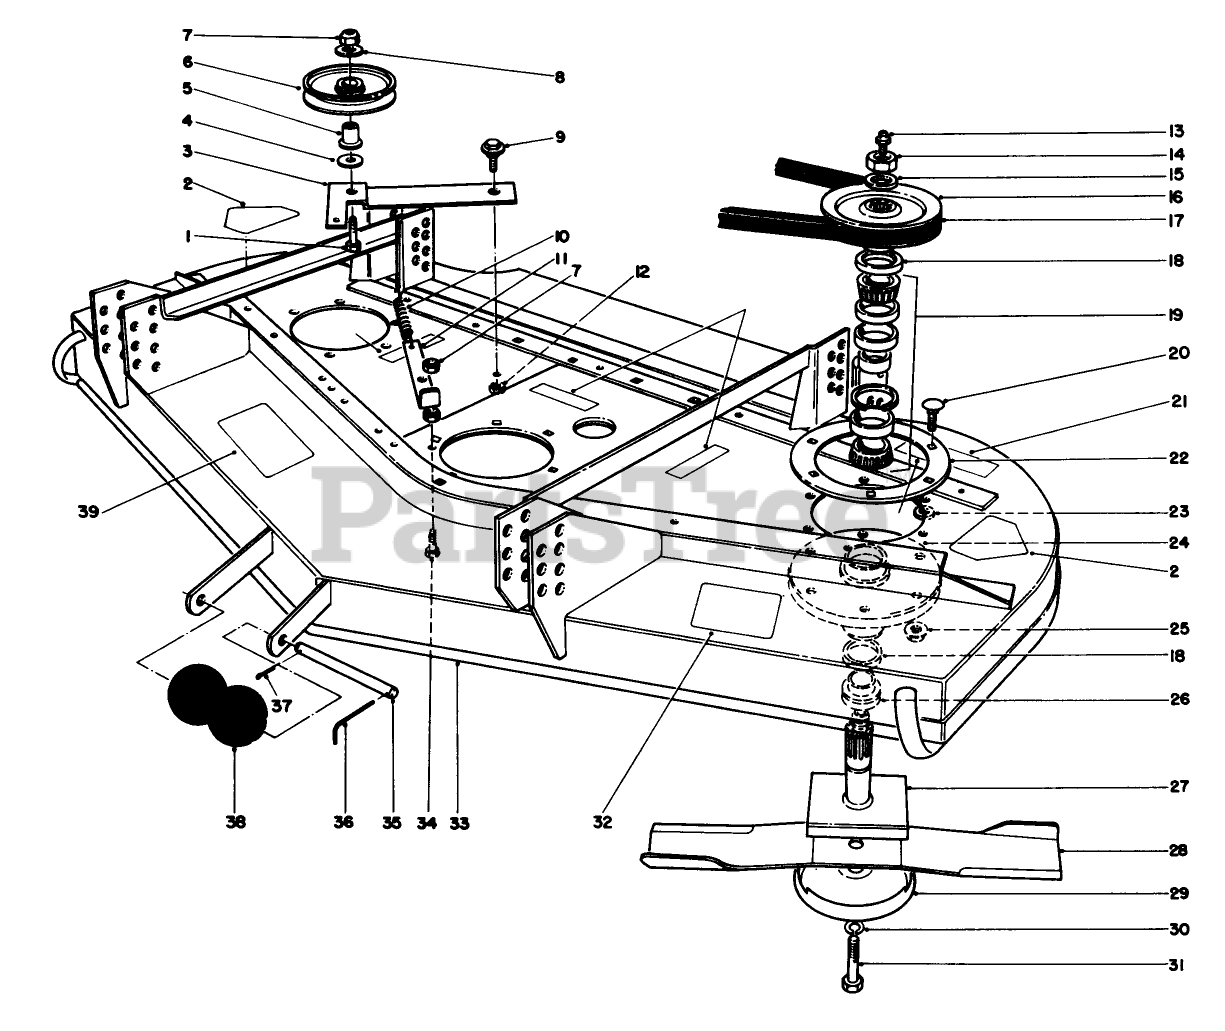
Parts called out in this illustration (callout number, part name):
1	SCREW-HH
2	DECAL-DANGER
3	Lever-Deck
4	WASHER
5	BUSHING-PULLEY
6	Pulley (Incl. Ref. #4 & 5)
7	NUT-LOCK, SIDE
8	WASHER-FLAT
9	SCREW-SHOULDER
10	SPRING-EXTENSION, DECK
11	Anchor-Spring
12	NUT-LOCK, NI
13	DECAL-DANGER
14	DECAL-TORQUE
15	FITTING-GREASE
16	NUT-HEX
17	WASHER
18	PULLEY & HUB WA
19	V-BELT, DECK
20	SEAL-OIL
21	BEARING ASM
22	SCREW-CARR
23	DECAL-WARNING
24	SUPPORT-DECK, RING
25	WASHER-FLAT
26	HOUSING-SPINDLE
27	NUT-HF
28	SPACER
29	SHAFT
30	Blade
31	Cup-Scalp
32	WASHER-LOCK
33	Screw-Blade
34	DECAL-DANGER, THROWN OBJECT
35	RD CUTTING DECK WA R
36	SCREW-HH
37	SHAFT-ROLLER
38	PIN-SPECIAL
39	PIN-COTTER
40	ROLLER
